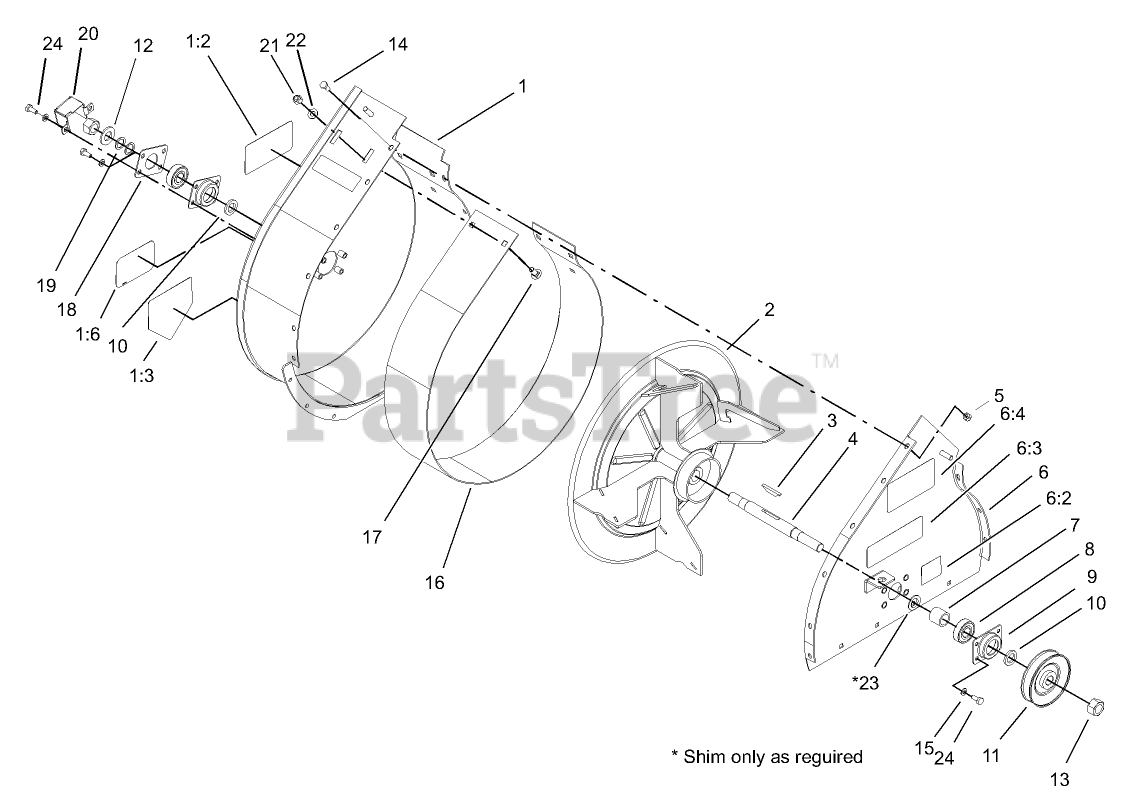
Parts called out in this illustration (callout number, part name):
1	Blower Housing ASM W/ Decals
1:2	DECAL-DANGER
1:3	DECAL-DANGER
1:6	DECAL
2	Impeller ASM
4	Shaft-Blower
5	NUT-LOCK, NI
6	Cover Plate ASM W/ Decal
6:2	DECAL-WARNING
6:3	DECAL-DANGER
6:4	DECAL-DANGER
7	Spacer
8	BEARING-BALL
9	CUP-BEARING
10	SPACER-BEARING
11	Pulley ASM
12	WASHER-FLAT
13	NUT-HEX
14	SCREW-HH
15	WASHER-LOCK
16	STRIP-WEAR
17	BOLT-CARR
18	PLATE-COVER
19	WASHER-FLAT
20	Cover-Shaft
21	NUT-LOCK, NI
22	WASHER-PLAIN
23	WASHER-THRUST
24	SCREW-HH
